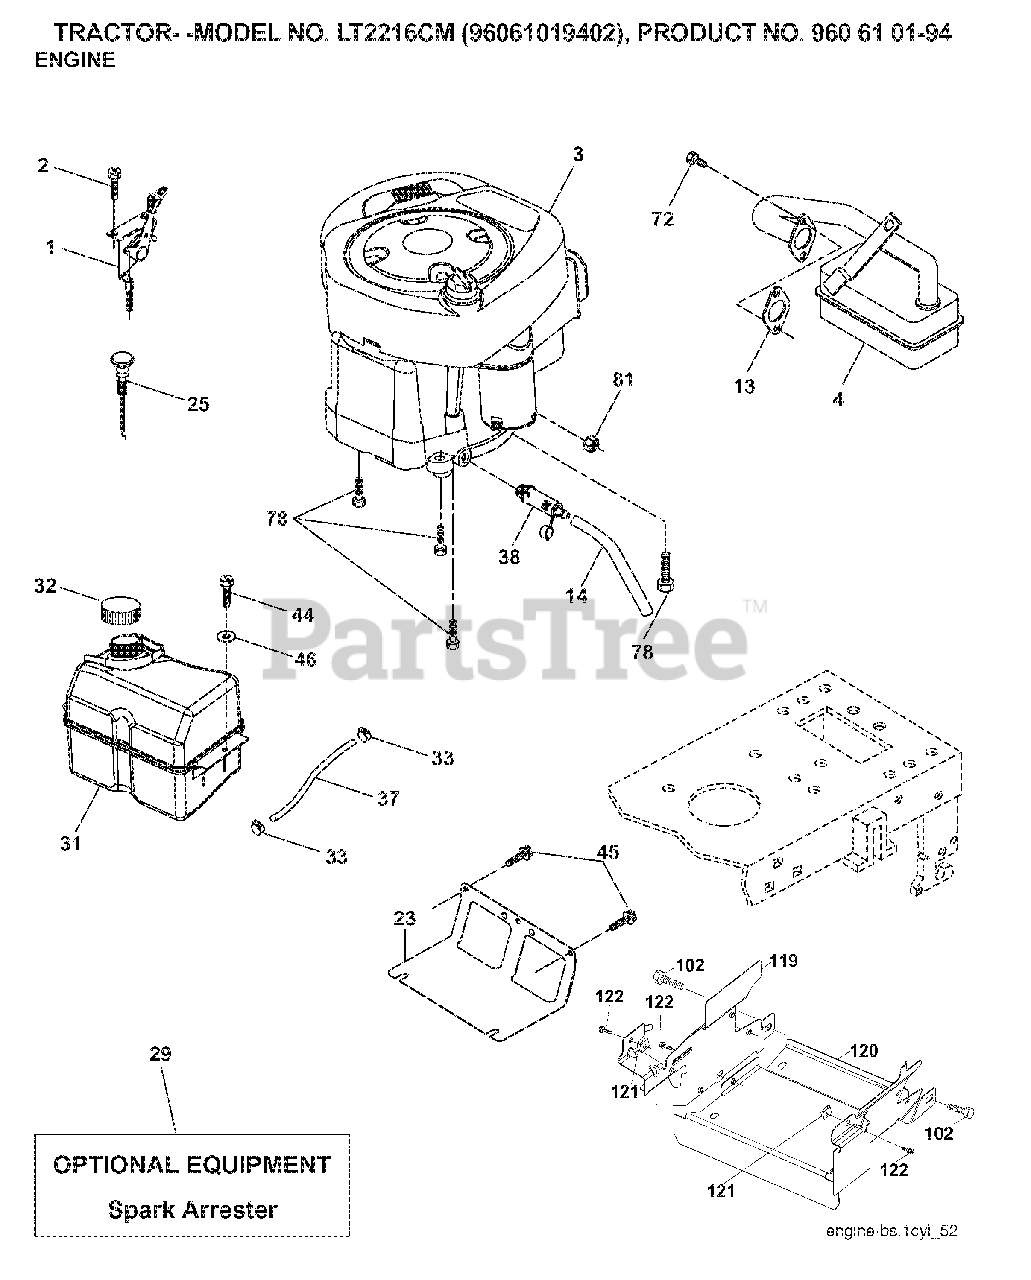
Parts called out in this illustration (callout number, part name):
1	CONTROL TH/CH FLAG
2	SCREW
13	REPL BY 532 27 22-93
14	TUBE, DRAIN OIL ASM.
23	SHEILD.BROWNING.DBR.GUARD
29	ARRESTER SPARK (OPTIONAL)
31	TANK FUEL
32	FUEL CAP
33	HOSE CLAMP
37	LINE.FUEL.20
38	PLUG DRAIN OIL EASY
44	SCREW HEXWSHR 1/4-20X3/4
45	SCREW, 3/8-16X3/4
46	WASHER
72	SCREW.SOCKET HD.5/16-1
78	SCREW.3/8-16
81	NUT
102	SCREW
122	SCREW.1/4-20X5/8
